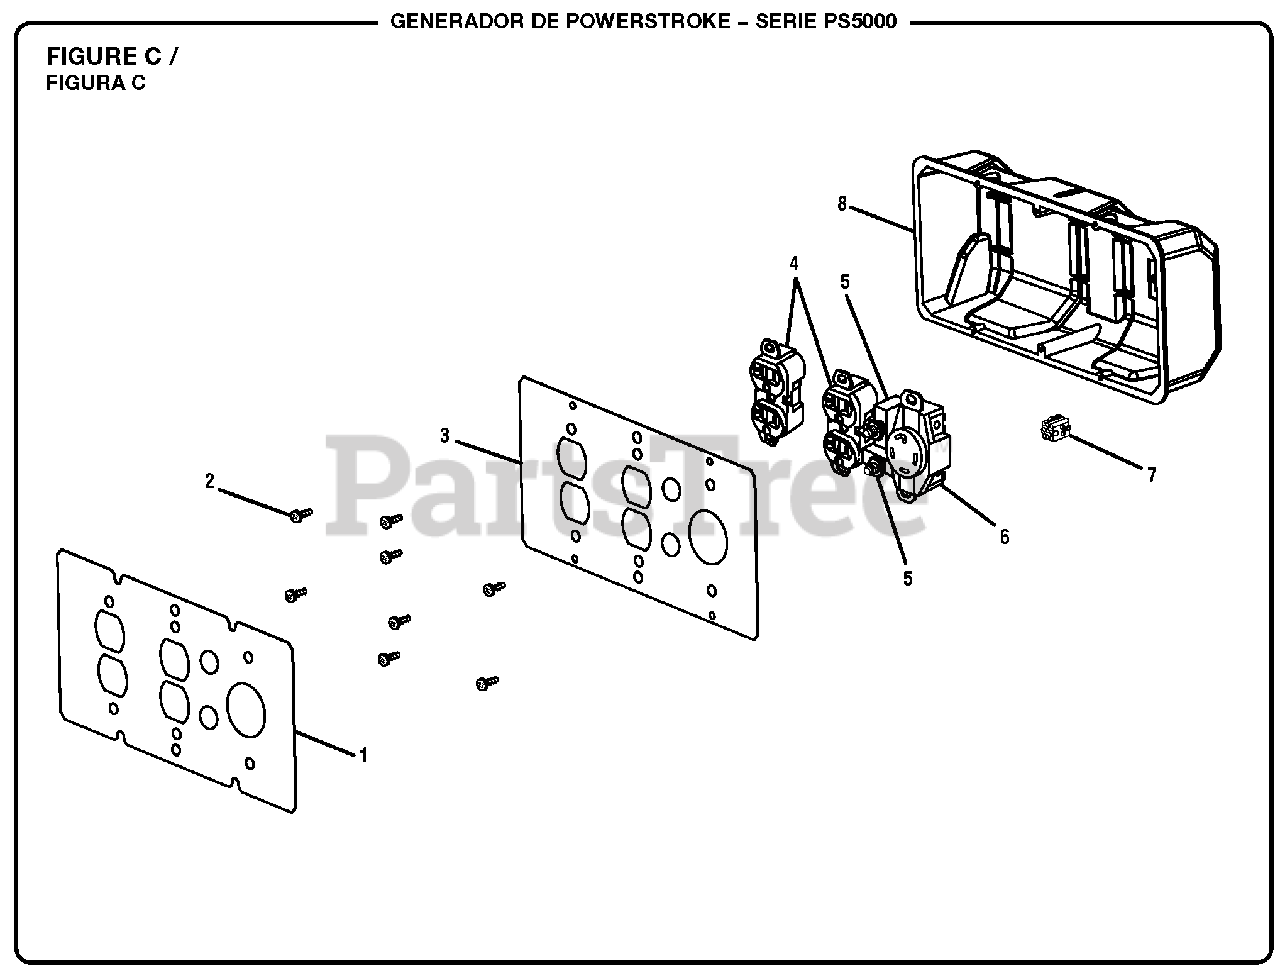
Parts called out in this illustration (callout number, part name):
1	Label (Power Outlet)
3	Front Panel
4	Duplex Receptacle
5	Circuit Breaker, 20 Amp
6	Twist Lock Receptacle
8	Control Box (Back Panel)
